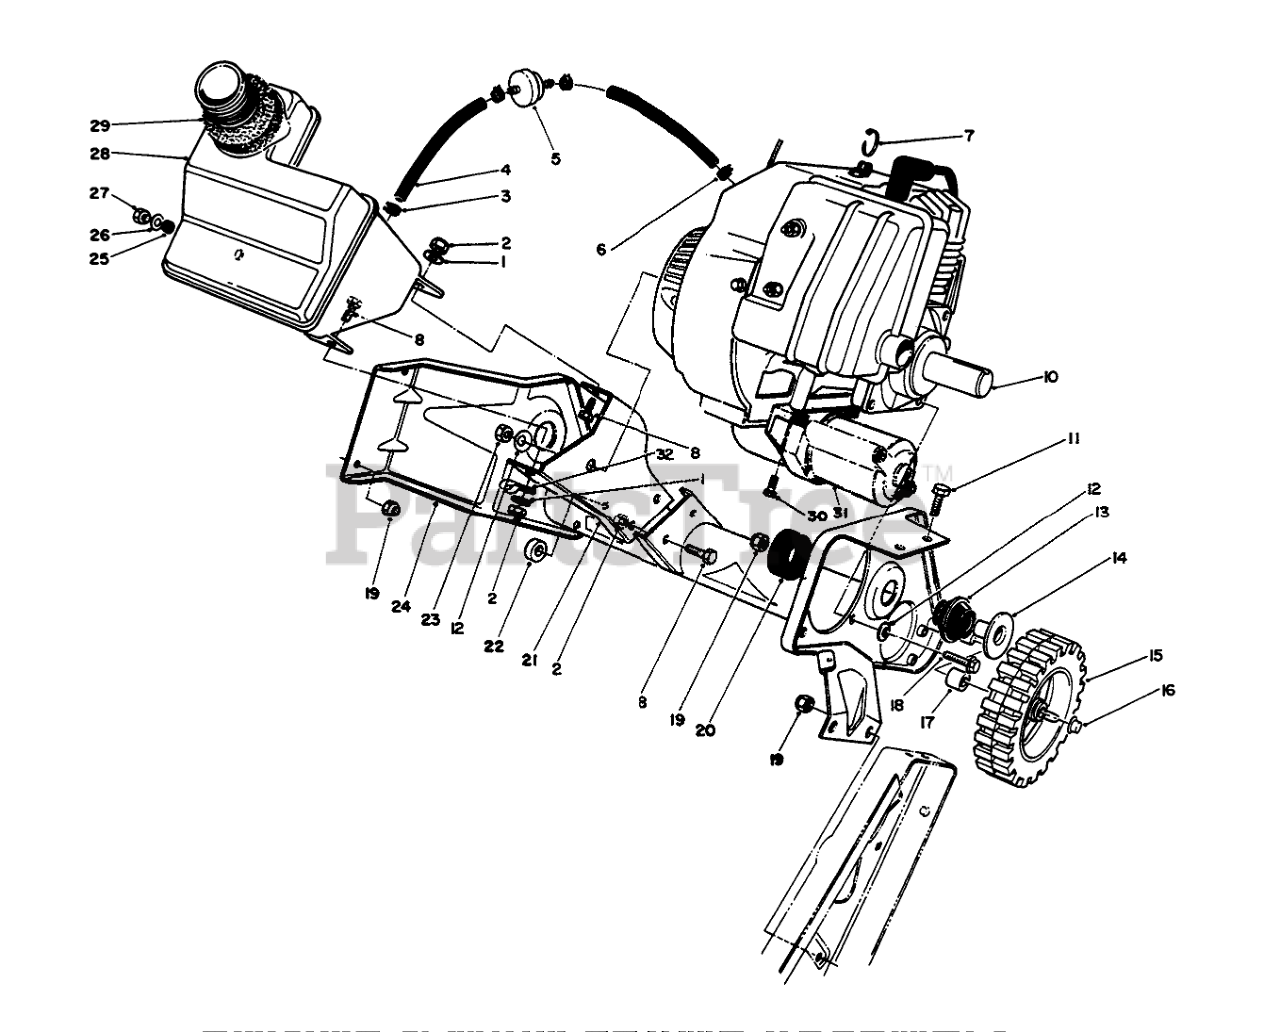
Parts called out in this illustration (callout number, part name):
1	WASHER-FLAT
2	NUT-LOCK, NI
3	Clamp
4	GAS LINE
5	FILTER-FUEL
6	CLAMP-HOSE
7	TIE-CABLE
8	SCREW-HH
10	Engine Assembly
11	SCREW-HH
12	WASHER-BELLEVILLE
13	MOUNT-REBOUND
14	SPACER TUBE
15	WHEEL
16	NUT-PUSH
17	SPACER-WHEEL
19	NUT-LOCK, NI
20	LOAD MOUNT
21	Support-Recoil
22	SPACER-WHEEL
23	NUT (F/W & PPP)
24	Wa-Frame
25	GROMMET-RUBBER
26	WASHER-PLAIN
27	NUT-LOCK, CONE
28	Tank-Fuel (Incl. Ref. #25)
29	SEAL-FOAM
30	SCREW
31	Starter Motor Assembly
32	CLAMP
